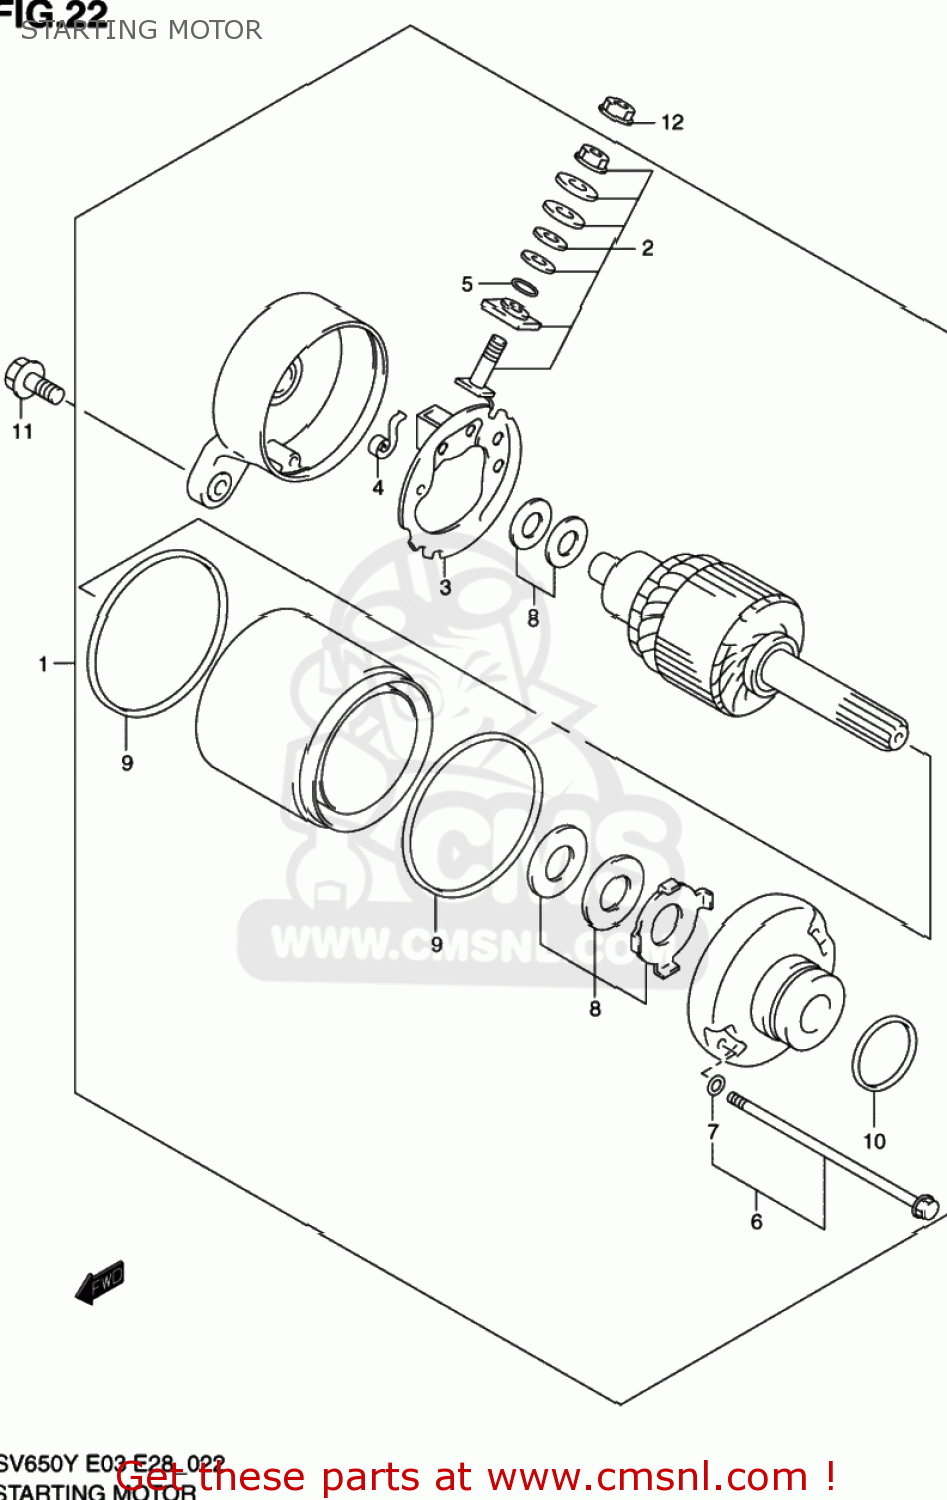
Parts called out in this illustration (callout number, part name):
1	MOTOR ASSEMBLY,STARTING
2	BRUSH TERMINAL SET
3	BRUSH HOLDER SET
4	SPRING,BRUSH
5	O RING
6	BOLT SET
7	O RING
8	SHIM SET,STARTING MOTOR
9	O RING
10	O RING(D:3.1,ID:24.4)
11	SCREW
12	NUT
